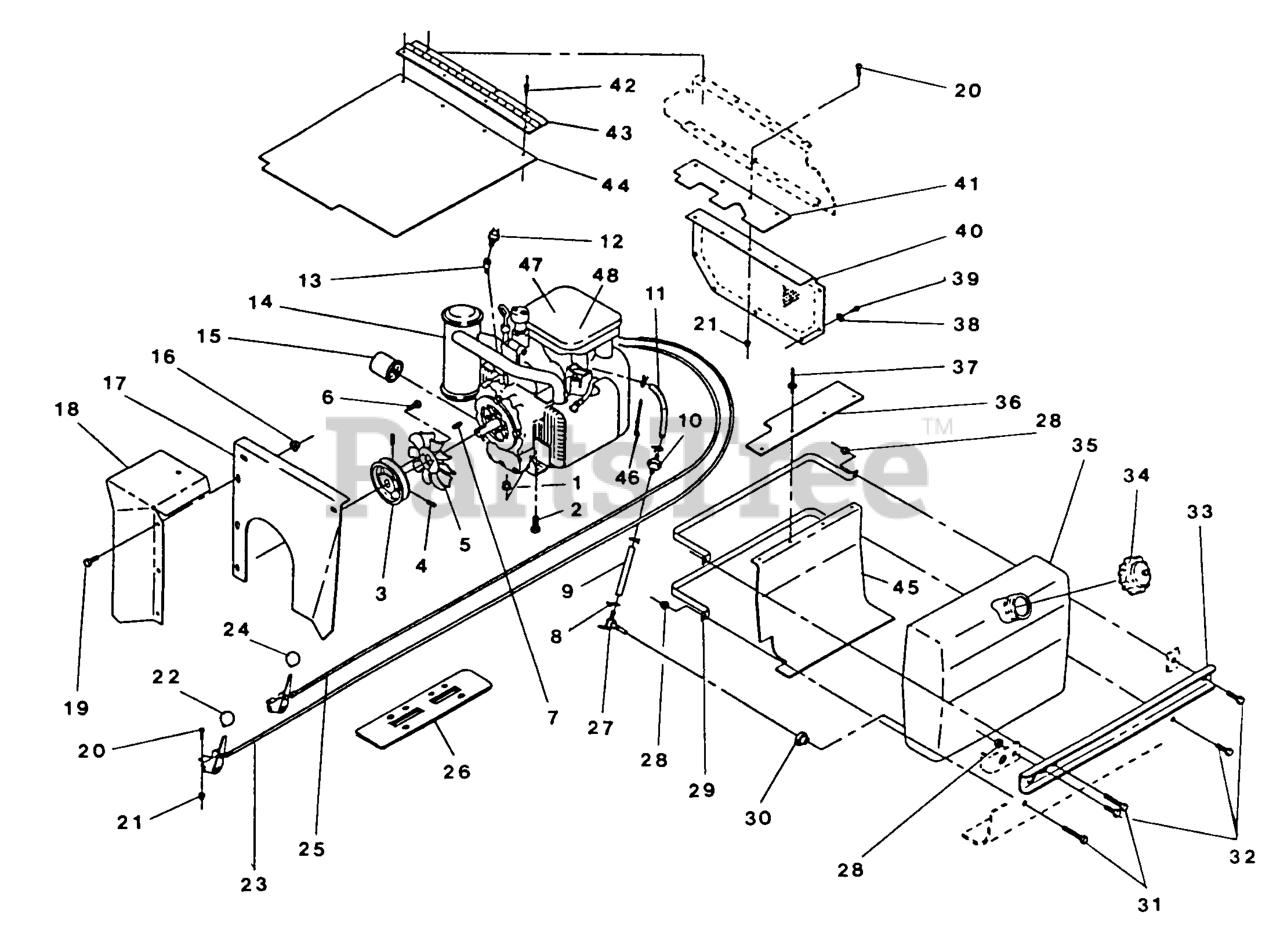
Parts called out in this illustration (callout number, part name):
4	SCREW-SET
9	HOSE-FUEL
11	FUEL LINE
17	SHIELD,HEAT FRONT
22	KNOB-BALL
24	KNOB-BALL, BLACK
29	STRAP,FUEL TANK 3.8GAL
31	Bolt, Tap 1/4-20 X 2-1/2
34	CAP-FUEL
36	BAFFLE,ENGINE LH
37	RIVET-POP
42	Pop Rivet, Steel 3/16 X .250
43	HINGE,ENGINE COVER
46	TIE-CABLE
